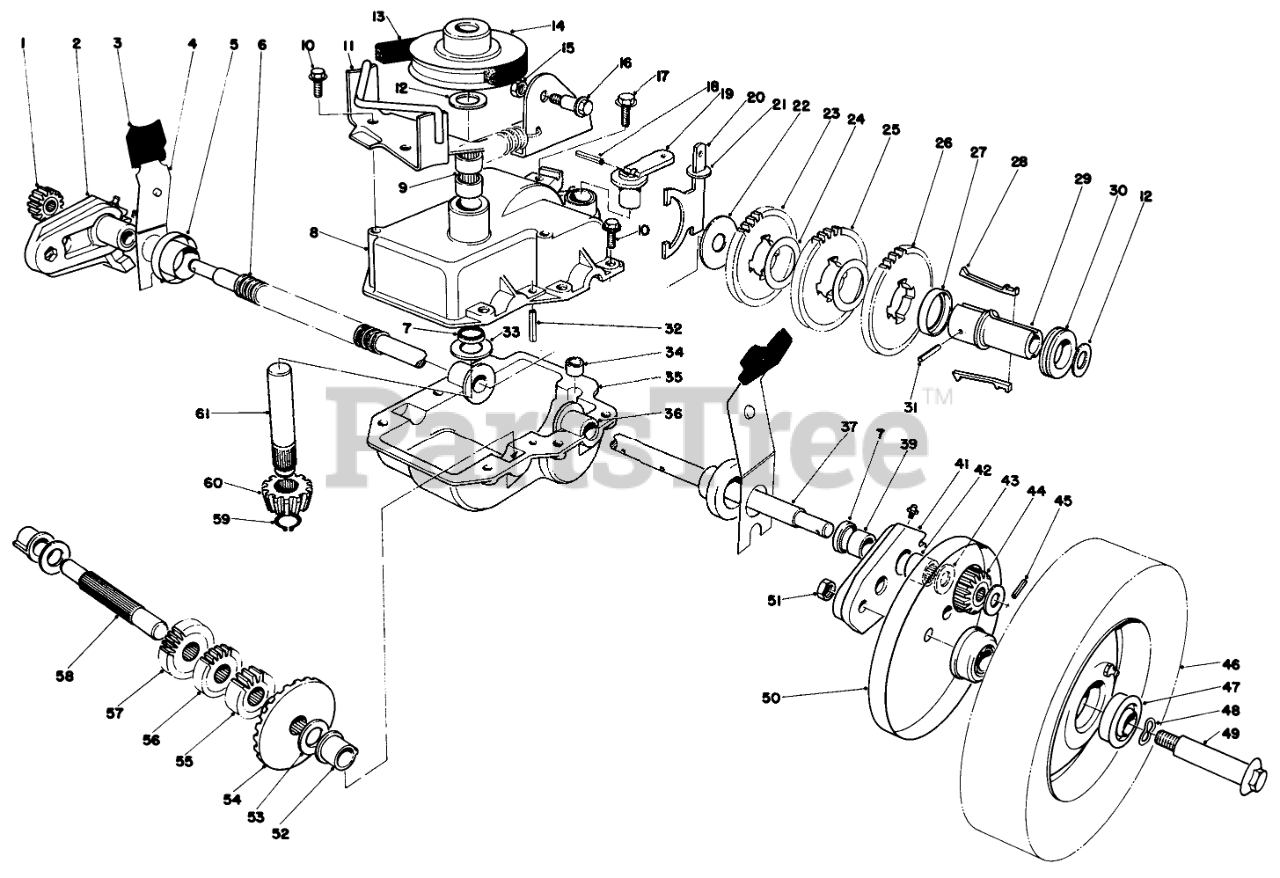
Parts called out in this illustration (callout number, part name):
1	Pinion Gear
2	Pivot Arm R. H. (Incl. Ref. #7, 39)
3	KNOB-ARM
4	Spring Arm
5	End Cap
6	CONDUIT-CONVOLUTED, SPLIT
7	Seal
8	Case Upper
9	Bearing
10	Screw
11	Belt Guide Bracket
12	WASHER-PLAIN
13	V-BELT
14	Pulley
15	NUT-HEX, SIDE DEFORM
16	Shoulder Bolt
17	SCREW-HWHTF
18	PIN-COIL
19	LEVER-SHIFT
20	Shift Yoke
21	Yoke Washer
22	WASHER
23	Gear 38T
24	WASHER
25	Gear
26	Gear
27	Key Retainer
28	KEY-SHIFT
29	Sleeve
30	COLLAR-SHIFT
31	COIL PIN
32	ROLL PIN 3/16 X 1 IN
33	Thrust Washer
34	BUSHING-YOKE
35	LOWER GEAR CASE CAST
36	Bushing
37	OUTPUT SHAFT
39	Bushing
41	Pivot Arm L.H. (Incl. Ref. #7, 39 & 42)
42	Needle Baring
43	WASHER
44	Pinion Gear
45	Pin
46	WHEEL ASM
47	BEARING-BALL
48	SPRING WASHER
49	WHEEL BOLT
50	Cover-Wheel
51	Nut
52	Botching Shaft
53	WASHER-THRUST
54	Bevel Gear
57	Gear 18T
58	Short Shaft
59	RING-RETAINING
60	Pinion Bevel
61	Input Shaft & Pulley Assy. (Incl. Ref. #14)
